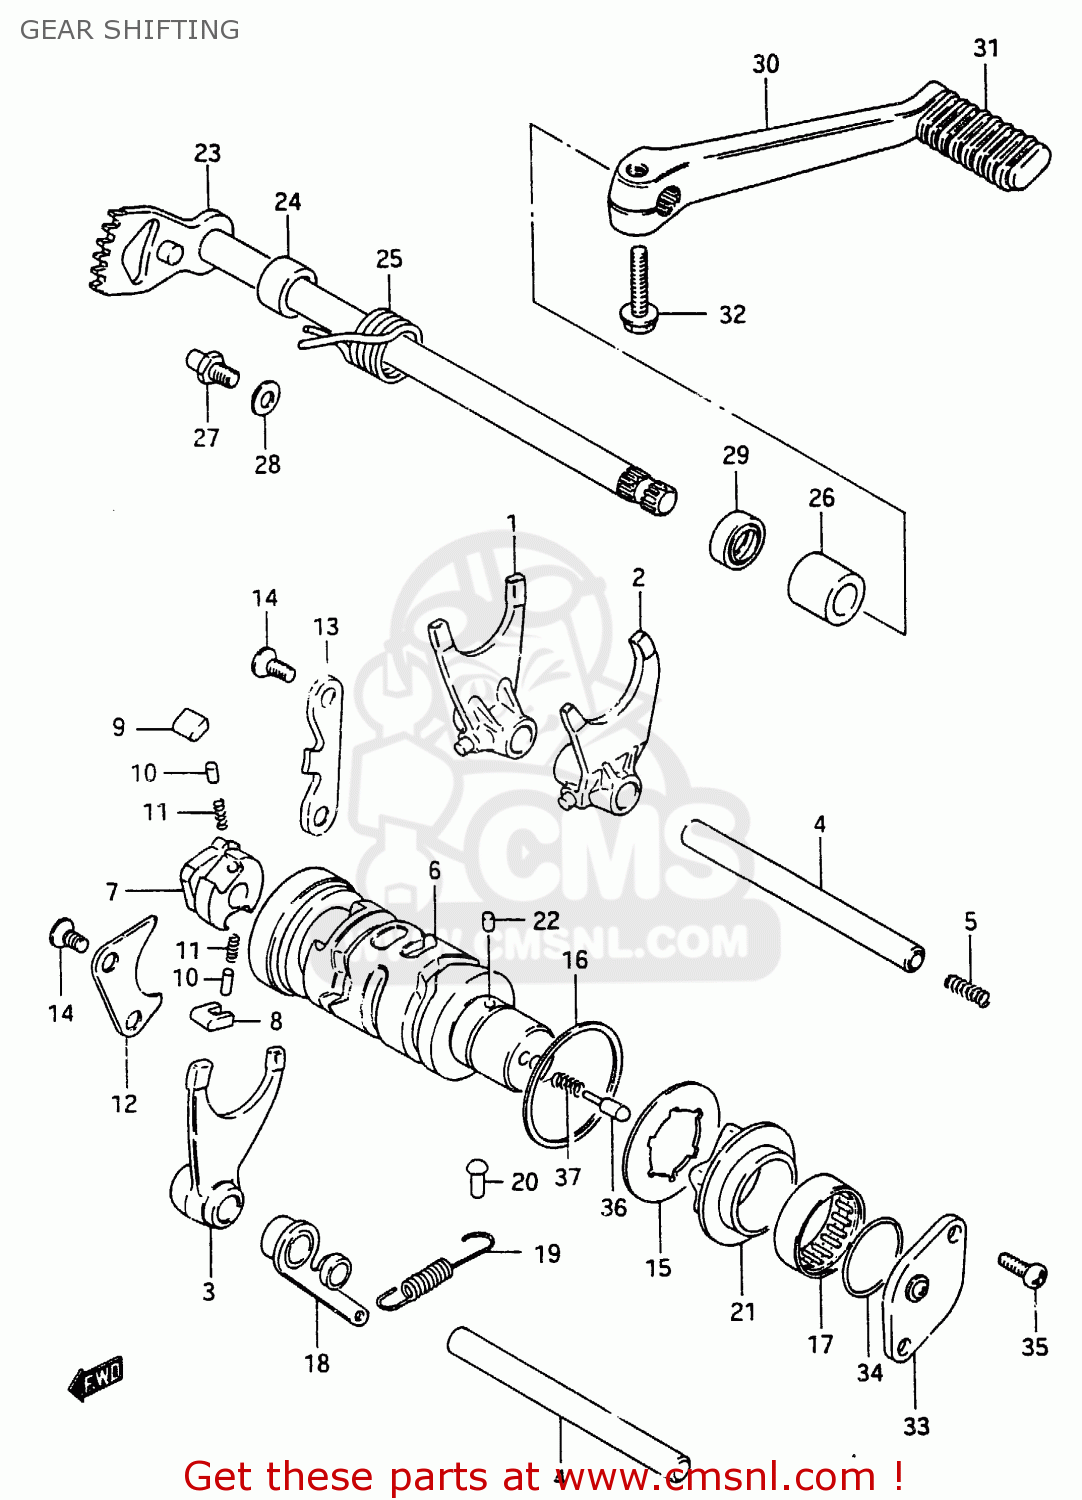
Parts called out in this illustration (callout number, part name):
1	FORK, GEAR SHIFT NO.1
2	FORK, GEAR SHIFT NO.2
3	FORK, GEAR SHIFT NO.3
4	SHAFT,GEAR SHIFT FORK(L:109)
5	SPRING
6	CAM, GEAR SHIFT
7	GEAR,GEARSHIFT CAM DRIVE
8	PAWL,GEAR SHIFT NO.1
9	PAWL,GEAR SHIFT NO.2
10	PIN(5X8)
11	SPRING
12	LIFTER,GEAR SHIFT POLE
13	GUIDE,GEAR SHIFT CAM
14	SCREW
15	WASHER,LOCK
16	WASHER
17	BEARING(25X32X12)
18	STOPPER, GEAR SHIFT CAM
19	SPRING
20	RIVET
21	PLATE,STOPPER
22	PIN 4X6
23	SHAFT, GEAR SHIFT
24	SPACER(12X20X15.3)
25	SPRING
26	CUSHION
27	STOPPER,GEAR SHIFT CAM
28	WASHER(8X17X2)
29	OIL SEAL
30	LEVER ASSY, GEAR SHIFTING
31	RUBBER,PEDAL
32	BOLT 6X25
33	BODY,GEAR SHIFT SWITCH
34	O-RING (D:2.4 ID:26.2)
35	SCREW
36	PIN(5X15.5)
37	SPRING
